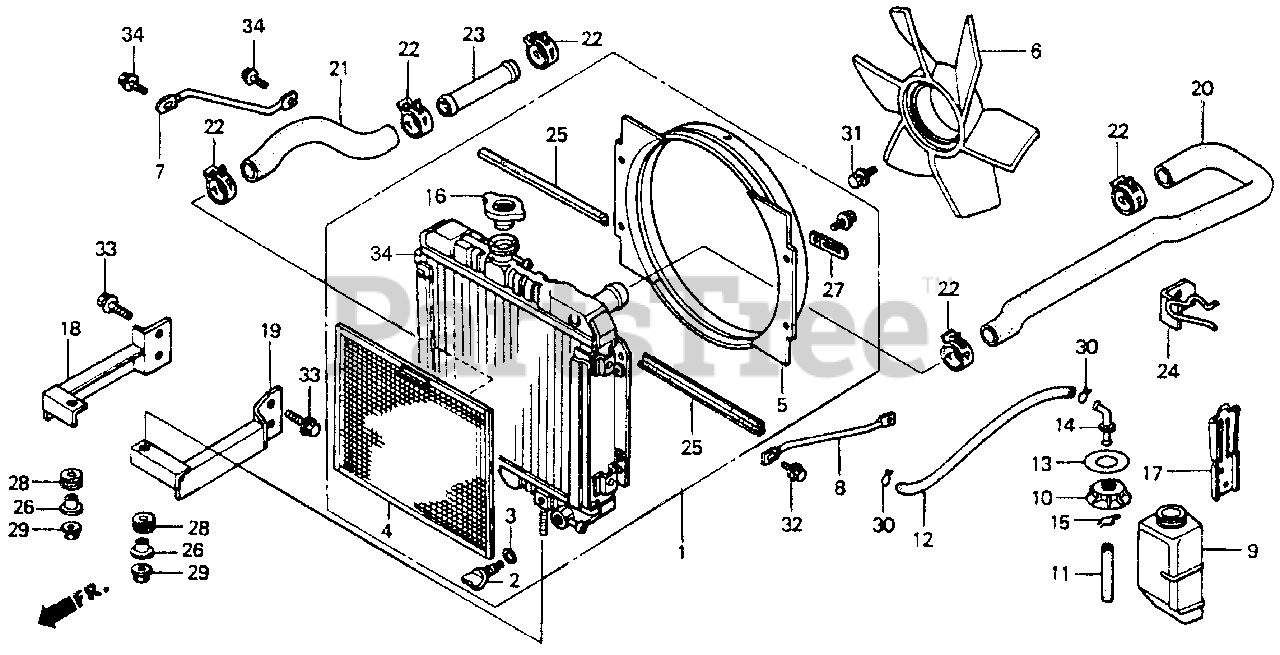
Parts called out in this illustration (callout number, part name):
1	RADIATOR ASSY.
2	VALVE, DRAIN (TOYO)
3	GASKET, DRAIN (TOYO)
4	SCREEN, FR.
5	SHROUD
6	FAN, COOLING
7	STAY, R. RADIATOR
8	STAY, L. RADIATOR
9	TANK ASSY., RESERVE
10	CAP, RESERVE TANK
11	HOSE, RESERVE TANK
12	TUBE, RESERVE TANK
13	MARK, RESERVE TANK
14	JOINT, RESERVE TANK
15	CLIP, RESERVE TANK JOINT
16	CAP, RADIATOR FILLER (TOYO)
17	BRACKET, RESERVE TANK
18	BRACKET, R. RADIATOR
19	BRACKET, L. RADIATOR
20	HOSE A, WATER (UPPER)
21	HOSE, WATER (LOWER) (A)
22	CLIP, WATER HOSE
23	PIPE, WATER HOSE JOINT
24	CLAMP, WATER HOSE (UPPER)
25	OIL SEAL, PAN MAINTENANCE (Honda Code 3639770). COVER
26	COLLAR, SEAT MOUNTING
27	CLIP (2X50)
28	CUSHION, TANK RUBBER
29	NUT, FLANGE (8MM)
30	CLIP, TUBE (C11)
31	BOLT, FLANGE (6X12)
32	BOLT, FLANGE (8X20)
33	BOLT, FLANGE (10X20)
34	RADIATOR
